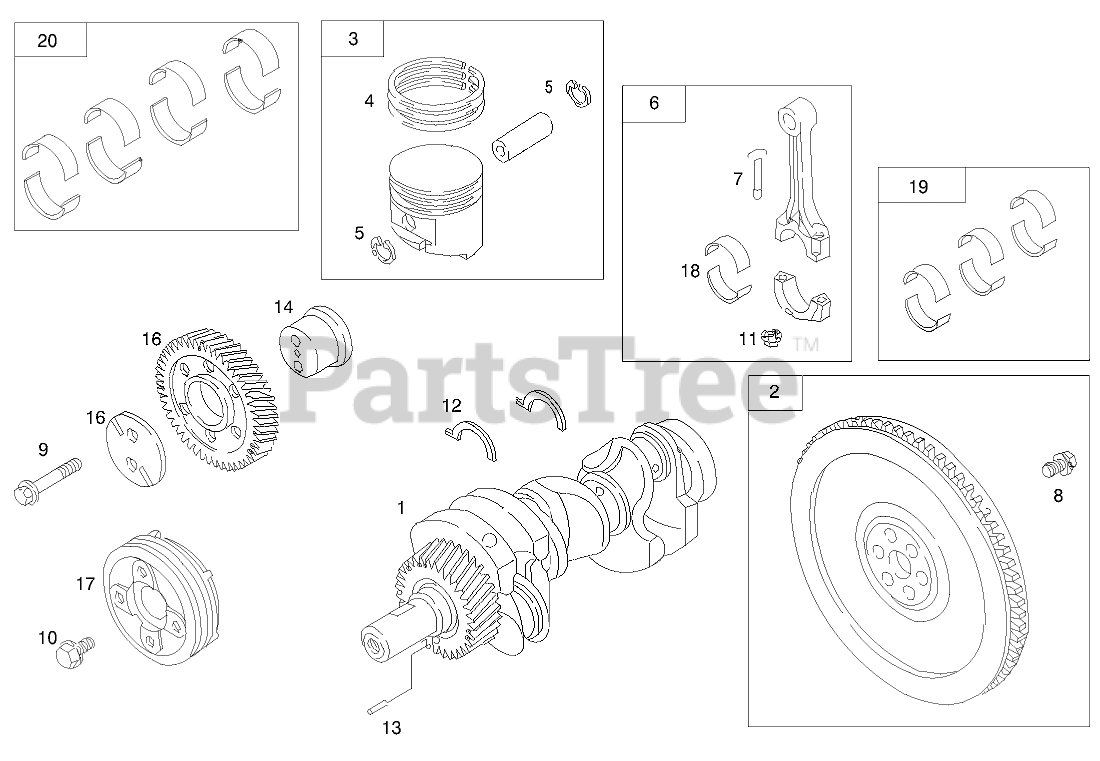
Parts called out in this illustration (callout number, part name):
1	Crankshaft
2	FLYWHEEL
3	PISTON ASM
4	RING SET
4	NIPPLE ASM
5	LOCK-PIN, PISTON
5	VALVE ASM
6	ROD-CONNECTING
7	SCREW-ROD, CONNECTING
8	SCREW-HEX
9	SCREW-HEX
9	GASKET-SET
10	SCREW-HEX
11	NUT-HEX
12	WASHER-THRUST
13	PIN-LOCATING
14	GEAR-DRIVE
14	VALVE OVERHAUL KIT
15	SHAFT-GEAR
16	PLATE-GEAR, IDLER
17	Pulley-Crankshaft
18	BEARING-ROD
19	SET-BEARING, ROD
20	SET-BEARING, MAIN (SET OF 8)
